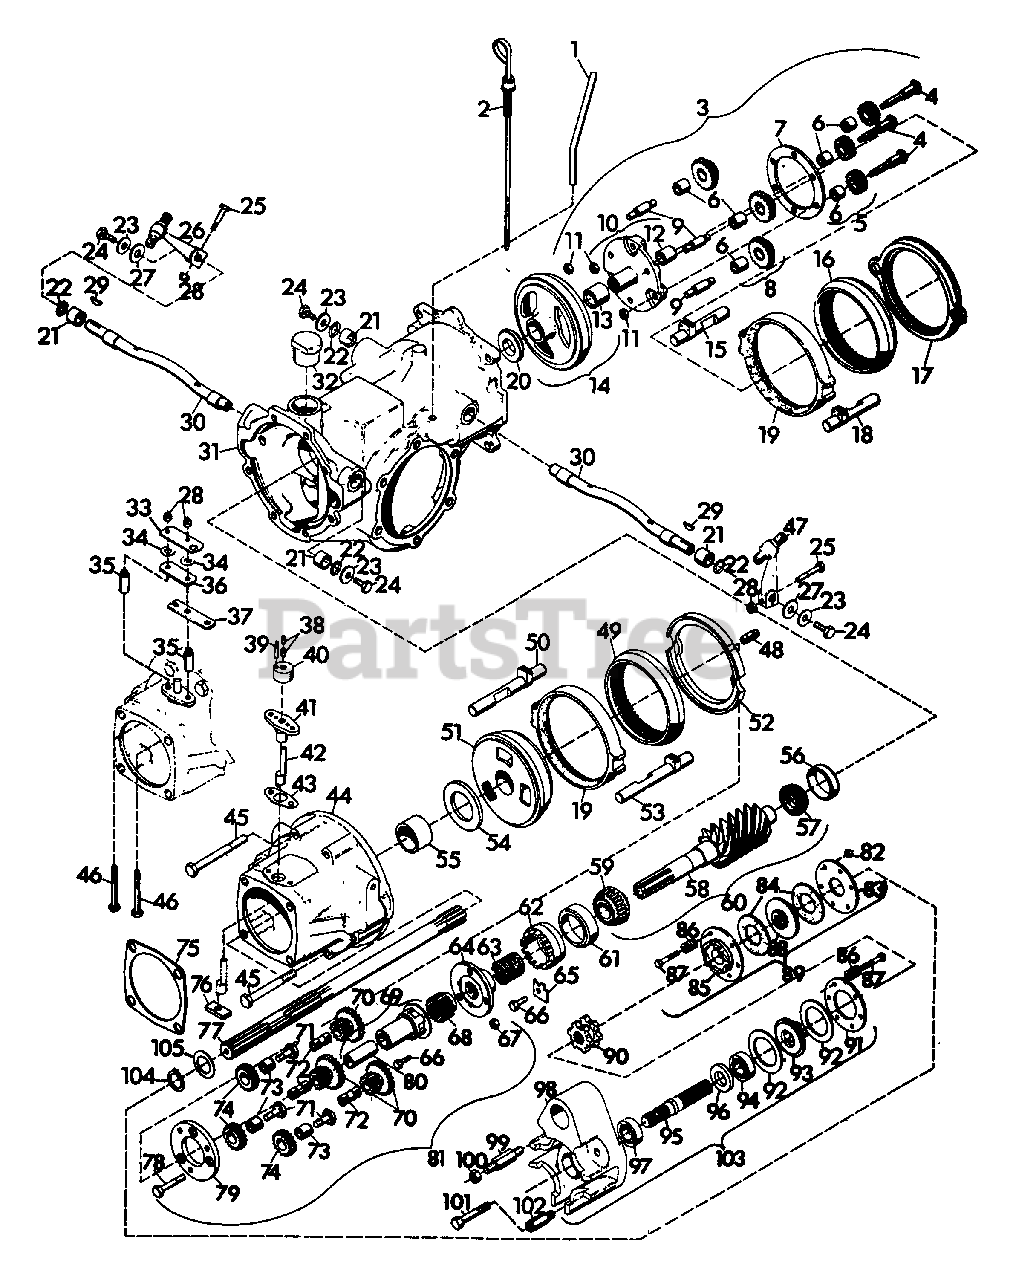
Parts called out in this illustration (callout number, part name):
1	Guide, Dipstick
2	Assembly, Dipstick
3	Assembly, Hi-Lo Planetary
4	Bolt, Orbit Gear
5	Assembly, External Orbit Gear
6	Bushing, .501 x .627 x .495
7	Spacer, Pin
8	Assembly, Internal Orbit Gear
9	Pin, Hi-Lo Orbit Gear
10	Assembly, Planet Gear Carrier
11	Nut, Locking 5/16-18 L.H. Thread
12	Bushing, .737 x .877 x .682
13	Bushing, 1.231 x 1.502 x .312
14	Assembly, Ring Gear and Bushing
15	Rod, Rear Clutch Slide L. H.
16	Gear, Rear Ring
17	Spacer, Rear
18	Rod, Rear Clutch Slide R. H.
19	Assembly, Clutch Cup
20	Plate, Rear Thrust
21	Bushing, .750 x 1.002 x .625
22	O-Ring, .750 x 1.00
23	Washer, Flat .265 x 1.250 x .063
24	Bolt, Hex 1/4-20 x .50
25	Bolt, Hex 5/16-18 x 2.00
26	Assembly, Fwd-Rev Lever
27	Washer, Flat .812 x 1.496 x .134
28	Nut, Lock 5/16-18
29	Key, Woodruff .125 x .625 Hard #5
30	Shaft, Actuating
31	Chassis
32	Plug, Oil Filler
33	Bracket, PTO Switch
34	Washer, Flat .344 x .688 x .065
35	Spacer, Shipper Shaft Guide
36	Spacer, Strap
37	Arm, Shifter
38	Screw, Set 3/8-16 x .25 HSCKT
39	Pin, spring .25 x .75
40	Body, Shipper Shaft
41	Guide, Shipper Shaft
42	Shaft, Shipper
43	Gasket, Shipper Shaft
44	Assembly, Advance Casting
45	Bolt, Hex 5/16-18 x 3.25 Gr. 8
46	Bolt, Hex 5/16-18 x 2.50
47	Assembly, Hi-LO Lever
48	Pin, Roll
49	Gear, Internal
50	Rod, Clutch Slide L. H.
51	Cone, Reverse Gear
52	Cup, Gear
53	Rod, Clutch Slide R. H.
54	Disc, Friction
55	Bearing
56	Cup, Roller Bearing
57	Cone, Roller Bearing
58	Weldment, 6-Lead Worm
58	Weldment, 8-Lead Worm
59	Cone, Roller Bearing
60	Welded Worm Shaft Assembly
61	Cup, Roller Bearing
62	Nut, Bearing Adjustment
63	Spacer, Spring Pin Plate
64	Plate, Front Pin
65	Nut, Adjusting
66	Bolt, Hex 1/4-20 x .625
67	Nut, Hex 1/4-20
68	Gear, Sun Pinion
69	Assembly, Quill and Bushing
70	Gear, Orbit
71	Bolt, Reverse Idler
72	Pin, Fed-Rev Orbit Gear
73	Bushing, Reverse Idler
74	Gear, Reverse Idler Spur
75	Gasket, Attachment
76	Block, Trunnion
77	Shaft, Pinion
78	Bolt, Spacer
79	Spacer, Front Pin
80	Bushing, .875 x 1.000 x 2
81	Assembly, Fwd-Rev Planetary
82	Nut, Jam 5/16-24
83	Plate, Back
84	Washer, Friction
85	Plate, Dog
86	Spring, Compression .75 x 2200 Rate
87	Bolt, Hex 5/16-24 x 1.75
88	Plate, Drive Splined
89	Assembly, Clutch
90	Dog
91	Plate, Back
92	Disc, Brake
93	Brake, Dog Plate
94	Bearing, Ball .984 x 2.097 x .591
95	Shaft, Quick Hitch
96	Seal, Oil
97	Bearing. Ball .984 x 2.047 x .590
98	Casting, Quick Hitch
99	Stud, Quick Hitch
100	Nut, Hex 1/2-13 x 1.00
101	Bolt, Hex 1/2-13 x1.00
102	Stud, Quick Hitch
103	Assembly, Attachment Adapter
104	Ring, Retaining
105	Race, Bearing Thrust
